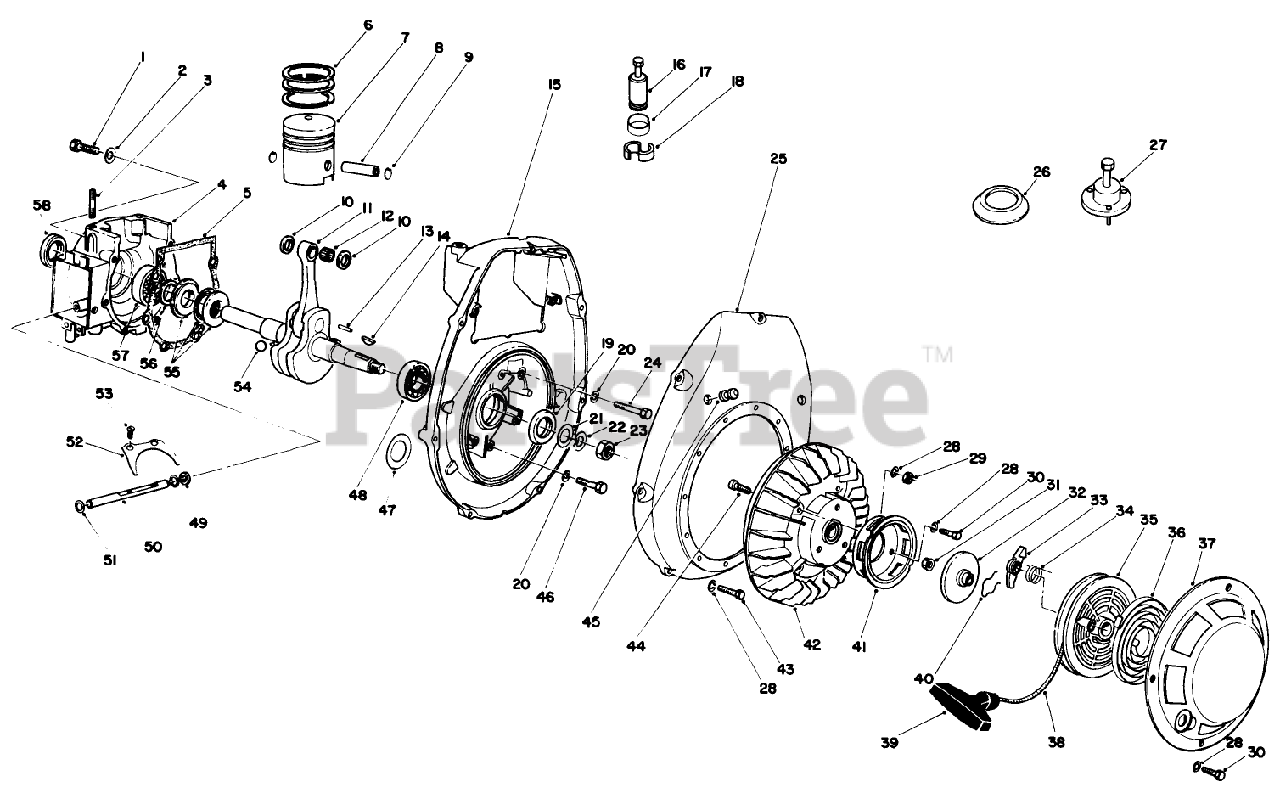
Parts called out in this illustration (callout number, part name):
1	CASE-SPECIAL
2	HOUSING-PINION
3	CAP-END, OPEN
4	SHAFT-PINION, SPECIAL
5	SHAFT-CROSS, SPECIAL
6	GEAR-SPIRAL, LH
7	GEAR-SPIRAL, RH
8	CUP-BEARING
9	CONE-BEARING
10	Ring-Retaining
11	CAP-END, CLOSED
21	KEY-WOODRUFF
49	RING-RETAINING
